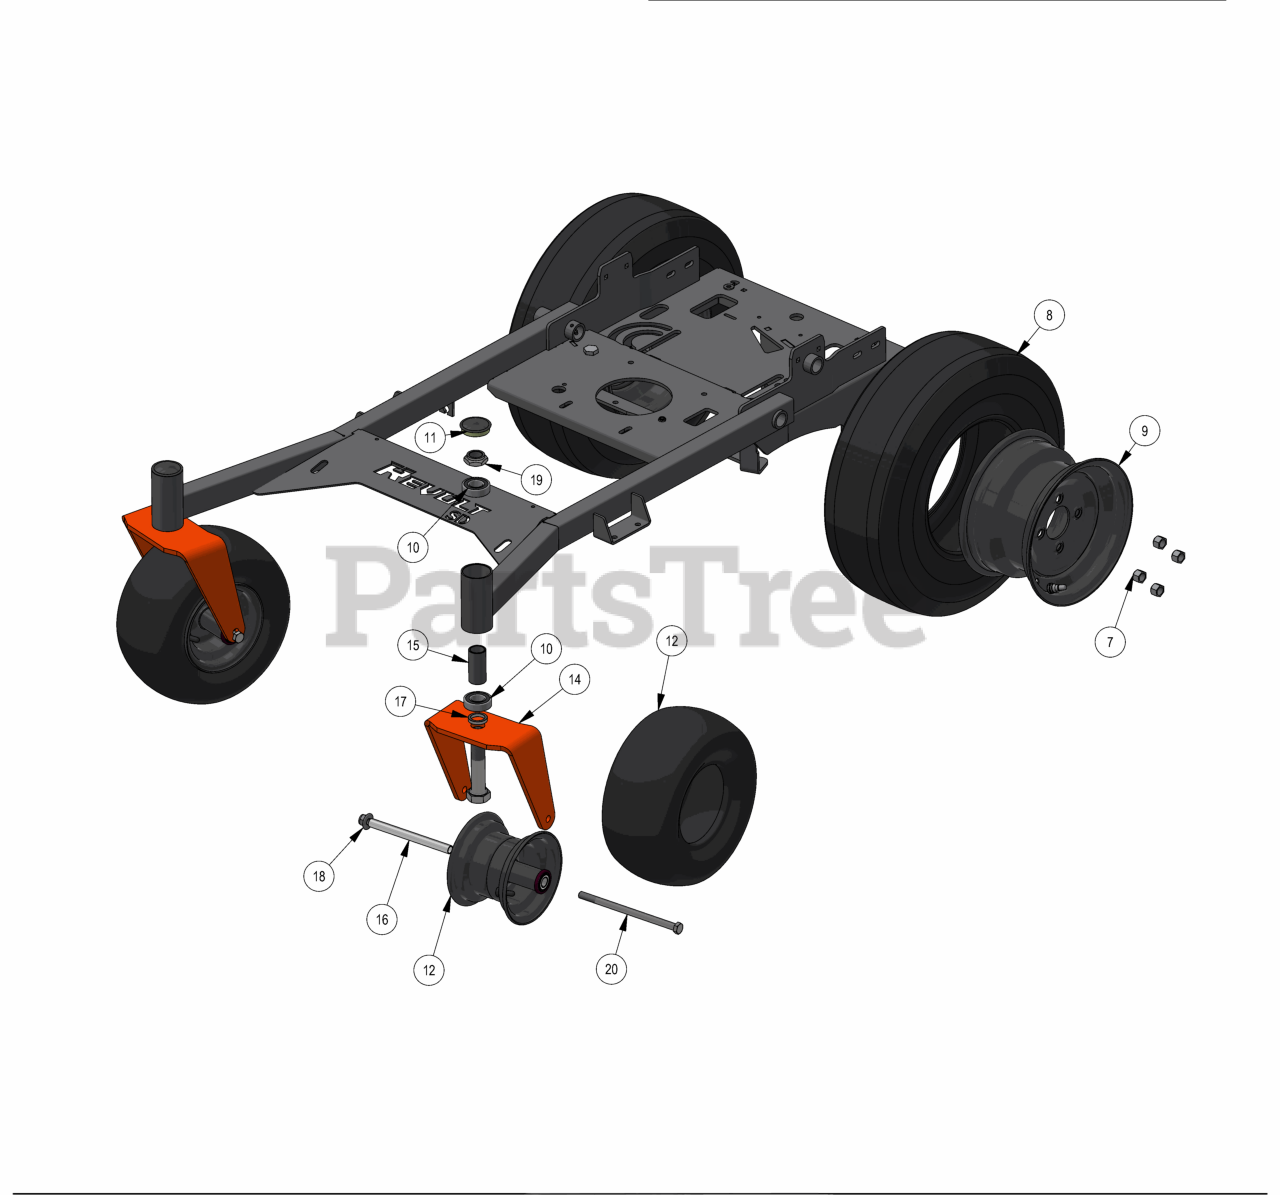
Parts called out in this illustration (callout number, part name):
1	1/2-13 Nylon Insert Nut
2	5/16-18 Nylock Jam Nut
3	1/2 Flat Washer
4	1/4 DRIVE-TYPE STRAIGHT GREASE FITTING (NO BALL) ZINC
5	2023 Stand On Frame Weldment -SD
6	1/4 USS FLAT WASHER (3/4 OD) ZINC
7	Acorn Lug Nut
8	36" Revolt Reaper Tire
9	36" Revolt Wheel
10	1641 BEARING W/2 CONTACT RUBBER SEALS
11	2017 Bearing Cover
12	13x6.5-6 Black Tire and Wheel Assembly
13	1 3/8" Wheel Bearing
14	2017 ZT Front Fork
15	2016 Front Bearing Spacer
16	Front Wheel Spanner
17	1.02 ID X 1.38 OD X .250 THK SPACER ZINC
18	1/2-13 Nylon Flange Nut
19	1"-14 NYLON INSERT JAM LOCKNUT ZINC
20	1/2-13 X 8-1/2 HEX CAP SCREW (GR.5) ZINC
21	1"-14 X 5 HEX CAP SCREW (GR.8) ZINC YELLOW
